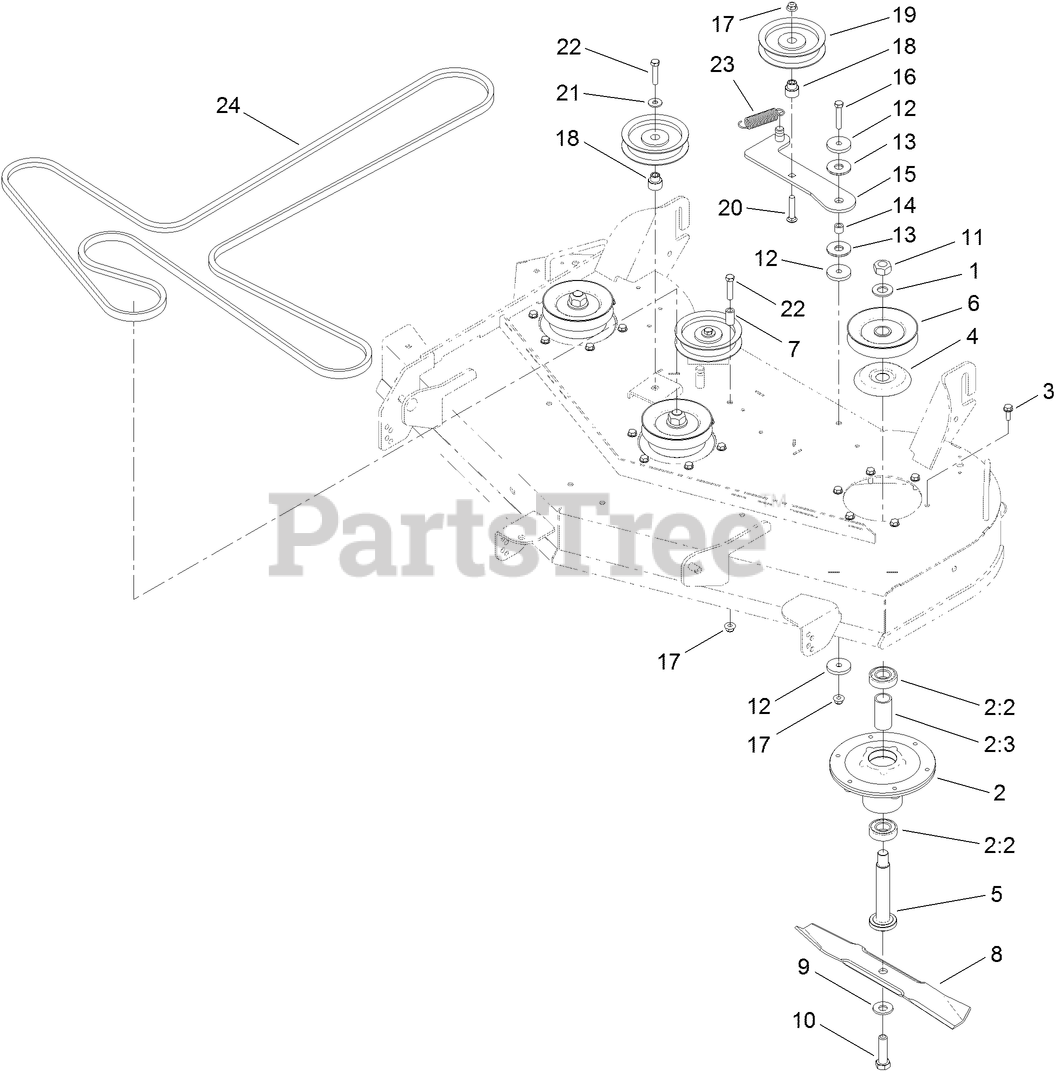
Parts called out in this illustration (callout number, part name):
1	WASHER
2	SPINDLE ASM
2:2	BEARING-BALL
2:3	SPACER-BEARING
3	SCREW-TAPTITE
4	SHIELD-BEARING
5	SHAFT-SPINDLE
6	PULLEY
7	SPACER
8	BLADE-MULCH, 16.50 INCH
10	SCREW-BLADE
11	NUT-HEX
12	WASHER-PLAIN
13	WASHER-FRICTION, COMPOSITE
14	BUSHING-LEVER, LIFT
15	ARM-IDLER
16	SCREW-HH
17	NUT-HF, NI
18	BUSHING-IDLER
20	SCREW-CARR
21	WASHER-HARDENED
22	SCREW-HH
23	SPRING-EXTENSION
